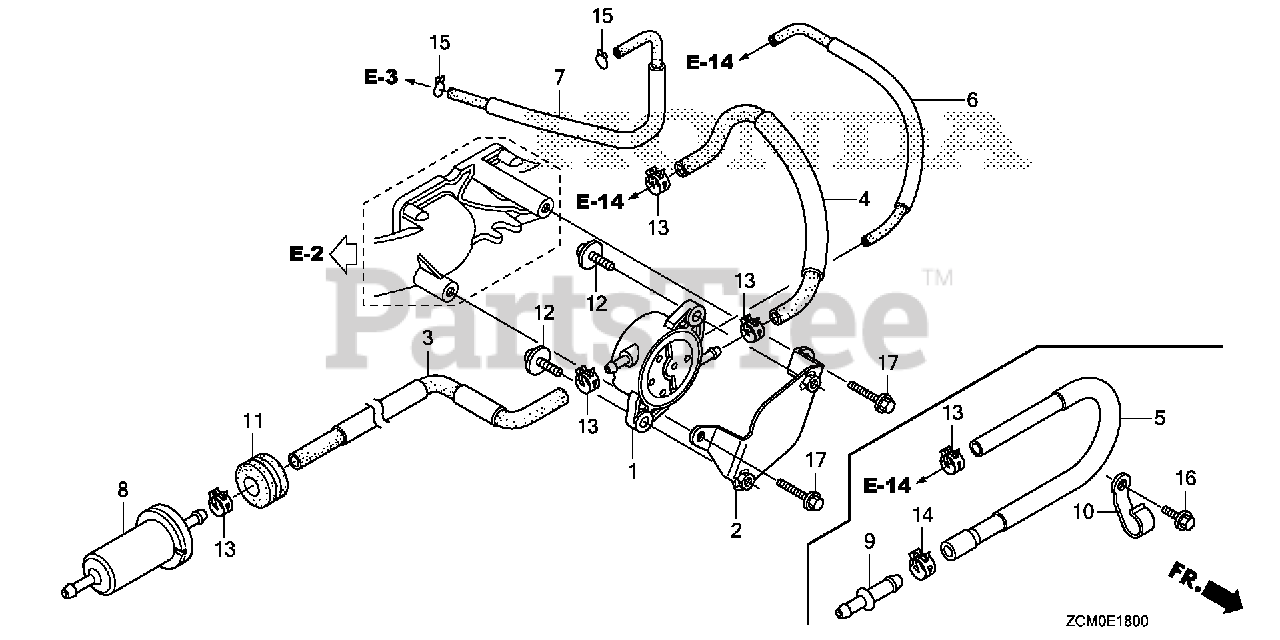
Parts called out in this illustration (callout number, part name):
1	PUMP ASSY., FUEL (MSDS)
2	STAY, FUEL PUMP
3	TUBE A, FUEL (FKM)
4	TUBE B, FUEL (FKM)
6	TUBE, PURGE
7	TUBE, DIAPHRAGM
8	STRAINER, FUEL
11	RUBBER, RR. FENDER
12	SCREW-WASHER (6X16)
13	CLAMP, TUBE (D10)
15	CLIP, TUBE (C11)
17	BOLT, FLANGE (6X14)
